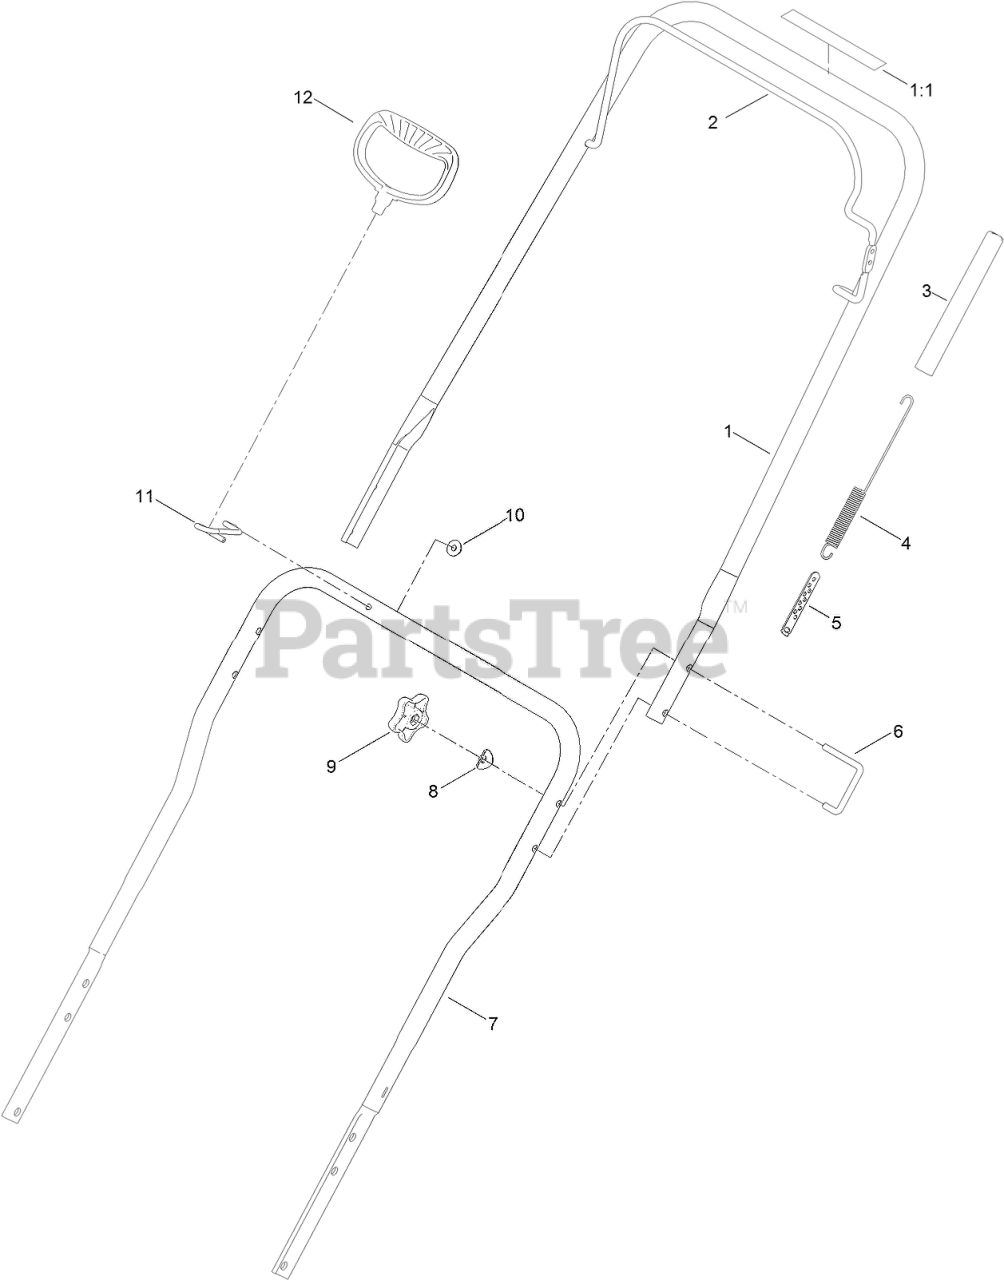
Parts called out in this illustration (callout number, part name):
1	UPPER HANDLE ASM
1:1	DECAL-DRIVE, ROTOR
2	BAIL-CLUTCH
3	COVER-SPRING
4	SPRING-EXTENSION, CLUTCH
5	ADJUSTER-CABLE, CLUTCH
6	LOCK-HANDLE
7	HANDLE-LOWER
8	WASHER
9	KNOB-HANDLE
10	NUT-HEX FLG
11	GUIDE-ROPE
12	HANDLE-RECOIL
